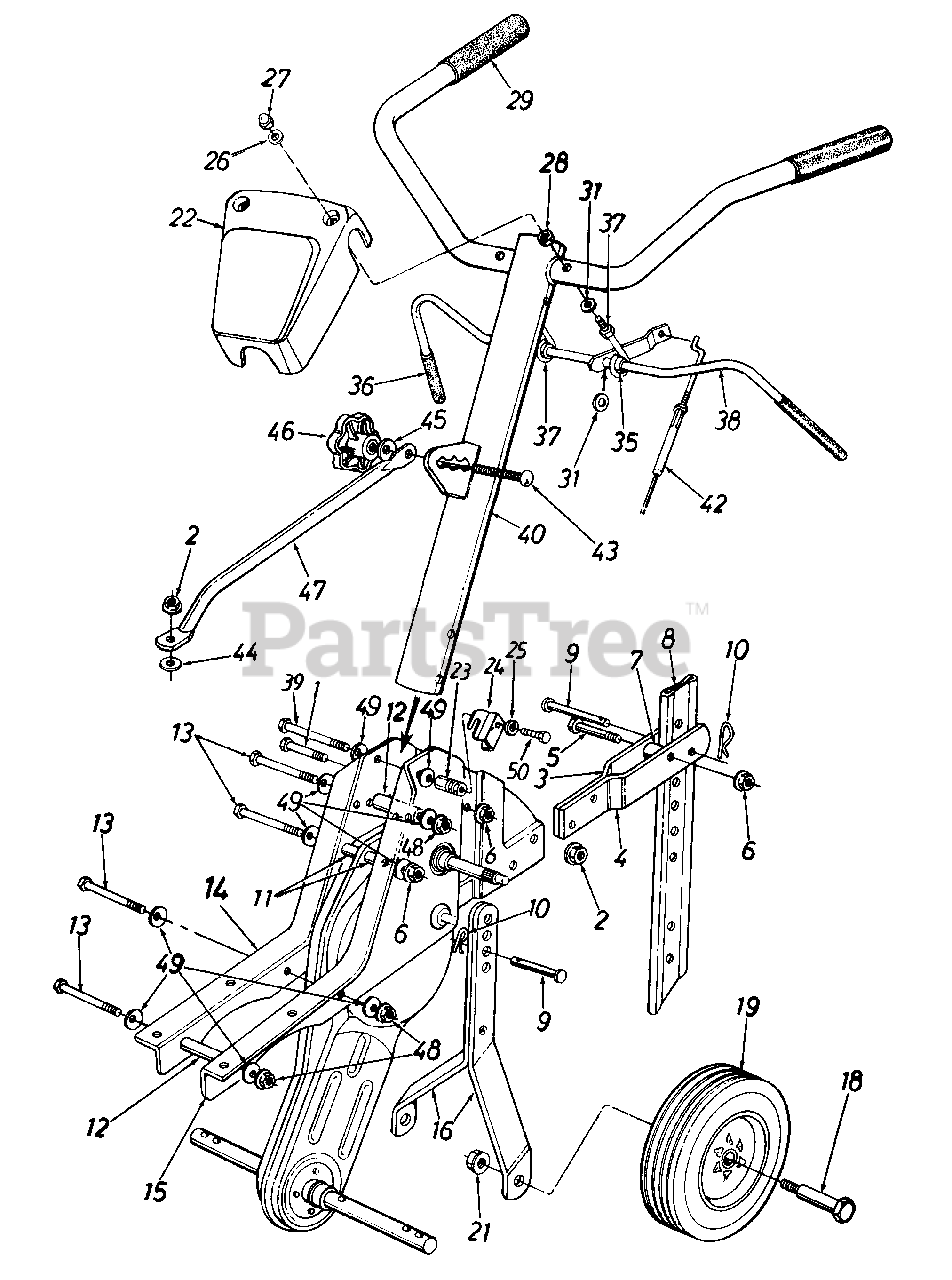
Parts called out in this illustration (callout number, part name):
1	Hex Bolt 5/16-18 x 1.25" Lg.
2	Hex Flange L-Nut 5/16-18 Thd. (Gr. 5)
5	Hex Bolt 5/16-18 x 1.5" Lg.
6	Hex Flange L-Nut 5/16-18 Thd. (Gr. 5)
7	Spacer .32" I.D. x .75" O.D.
9	Clevis Pin .375" I.D. x 1.75" Lg.
10	Internal Cotter Pin
11	Spacer .326" I.D. x .47" O.D.
12	Spacer .322" I.D. x .44" O.D.
13	Hex Bolt 5/16-18 x 2.75" Lg.
19	Wheel Ass'y.
21	Hex Flange L-Nut 3/8-16 Thd. (Gr. 5)
22	Handle Cover
23	Spec. Hex Nut
25	L-Wash. 5/16" I.D.
26	Fl-Wash. .266" I.D. x .625" O.D.
27	Hex L-Stop Nut 1/4-28 Thd.
28	Hex Nut 1/4-28 Thd.
29	Grip - Handle
31	Fl-Wash. .385" I.d. x .62" O.D.
35	Plastic Bushing .38" I.D.
36	Grip - Clutch
37	Clutch Handle Eye Bolt
43	Carr. Bolt 5/16-18 x 1" Lg. (Special)
44	Fl-Wash. .344" I.D. x 1.12" O.D.
45	Bell-Wash. .345" I.D. x .88" O.D.
46	Hand Knob
49	Bell-Wash. .345" I.D. x .88" O.D.
50	Hex Bolt 5/16-18 x .75" Lg. (Gr. 5)
